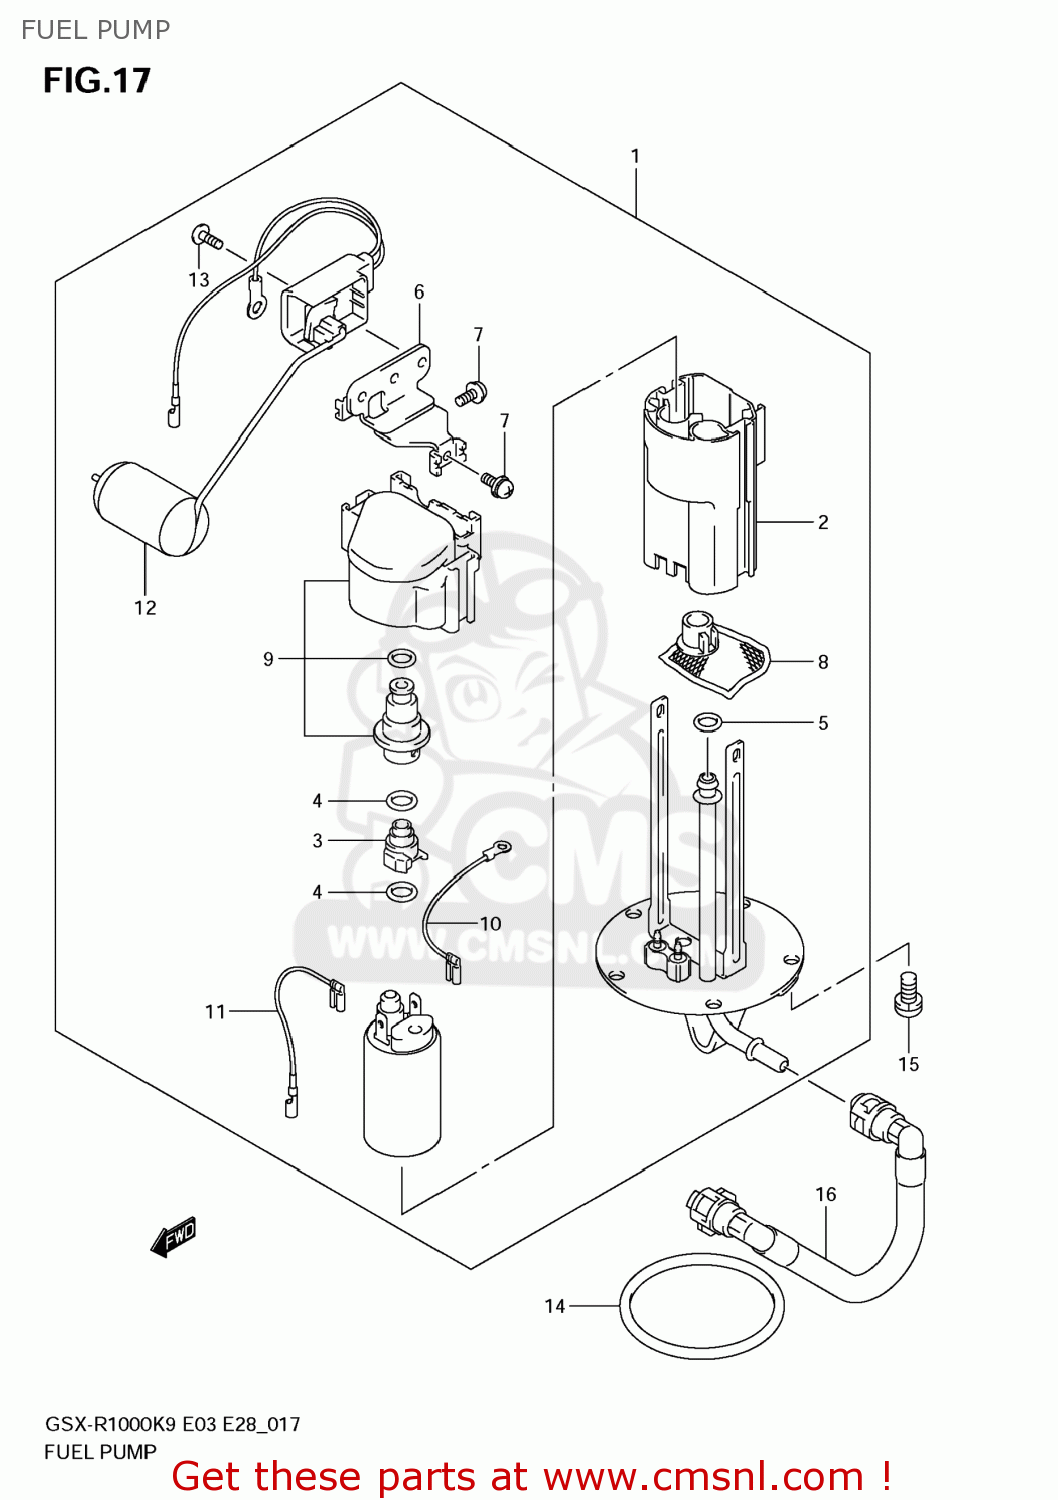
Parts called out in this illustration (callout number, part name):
1	PUMP ASSY,FUEL
2	CUP
3	JOINT
4	O RING
5	O RING
6	BRACKET
7	SCREW
8	STRAINER
9	REGULATOR
10	WIRE,EARTH
11	WIRE,LEAD
12	GAUGE ASSY,FUEL LEVEL SENDER
13	SCREW
14	O RING,FUEL PUMP
15	BOLT
16	HOSE,FUEL
